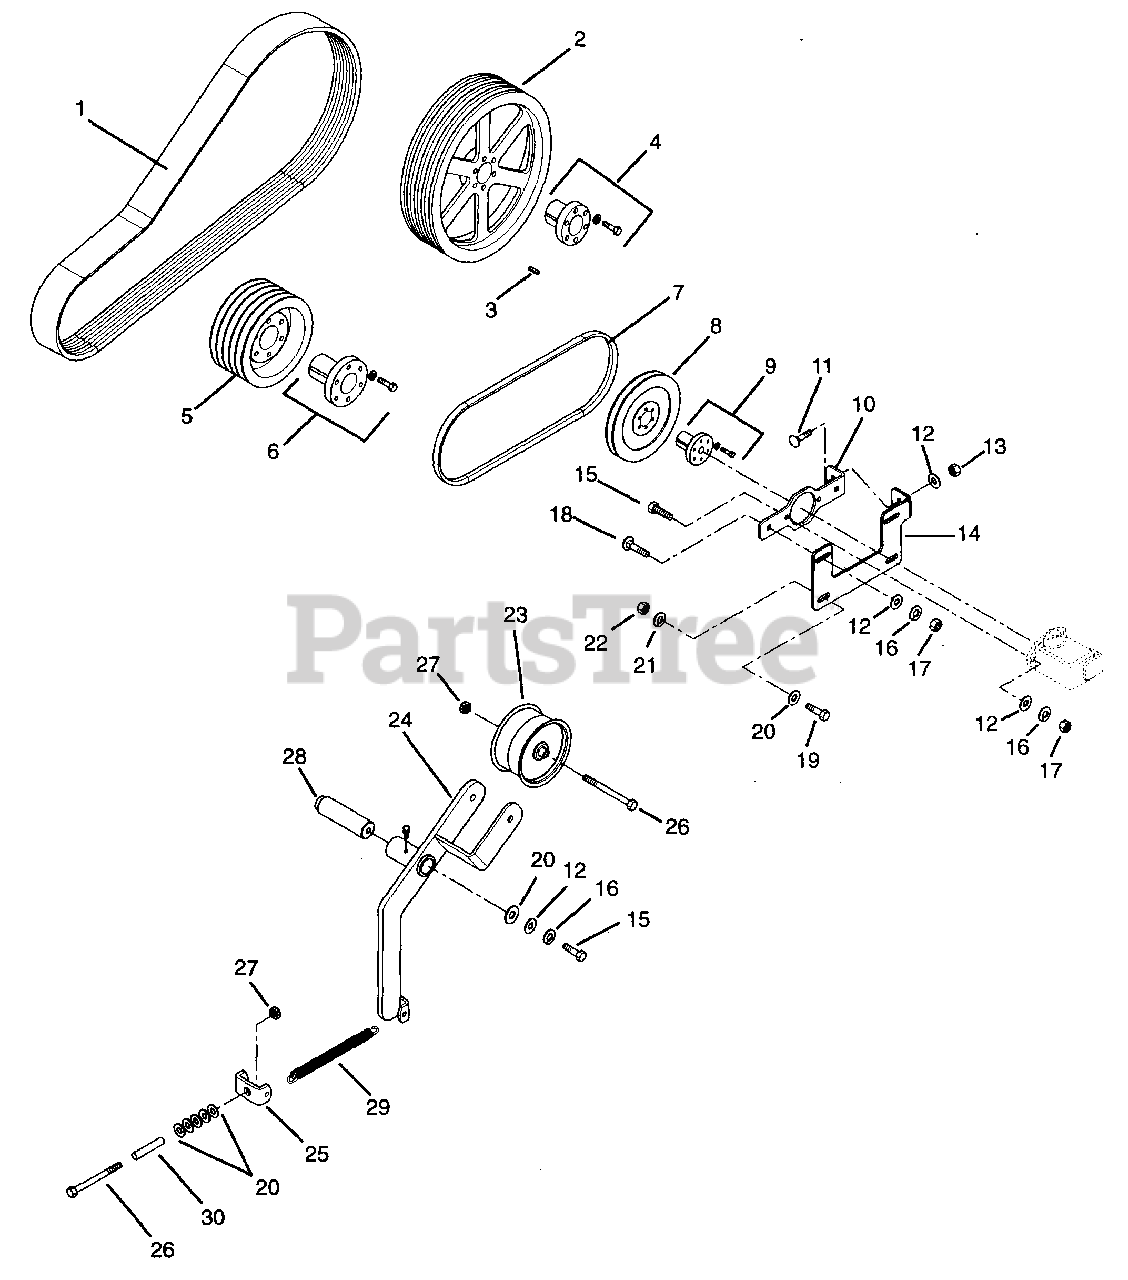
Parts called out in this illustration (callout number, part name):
1	Drive Belt
2	Pulley Driven 16 in
3	Key-Straight .50 x .50 x 1.75
4	Bushing-Sheave
5	Drive Sheave
6	Bushing-Sheave
7	V-Belt 23 HP Matched Set
8	Pump Sheave
9	Bushing-Sheave
10	Hydraulic Pump Bracket
11	Bolt-Round Head Square Neck .38-16 x 2.75
12	Washer-Flat-Steel .438 x 1.0 x .083
13	Nut-Locking .375-16
14	Hydraulic Pump Mount Bracket
15	Bolt-Hex .44-14 x 1.50 Grade 5
16	Washer-Lock .438 x .133
17	Nut .437-14
18	Bolt-Round Head Square Neck .44-14 x 1.50
19	Bolt-Hex .50-20 x .75 Grade 5
20	Washer-Flat-Steel .563 x 1.375 x .109
21	Washer-Lock .50 Reg
22	Nut .50-13
23	Pulley-Idler
24	Idler Arm Weldment
25	Spring Bracket
26	Bolt-Hex .50-13 x 6.00
27	Nut-Locking-Center .50-13
28	Idler Arm Rod
29	Spring-Tension .156 x 1.062 x 2.68
30	Spacer-Idler Spring
